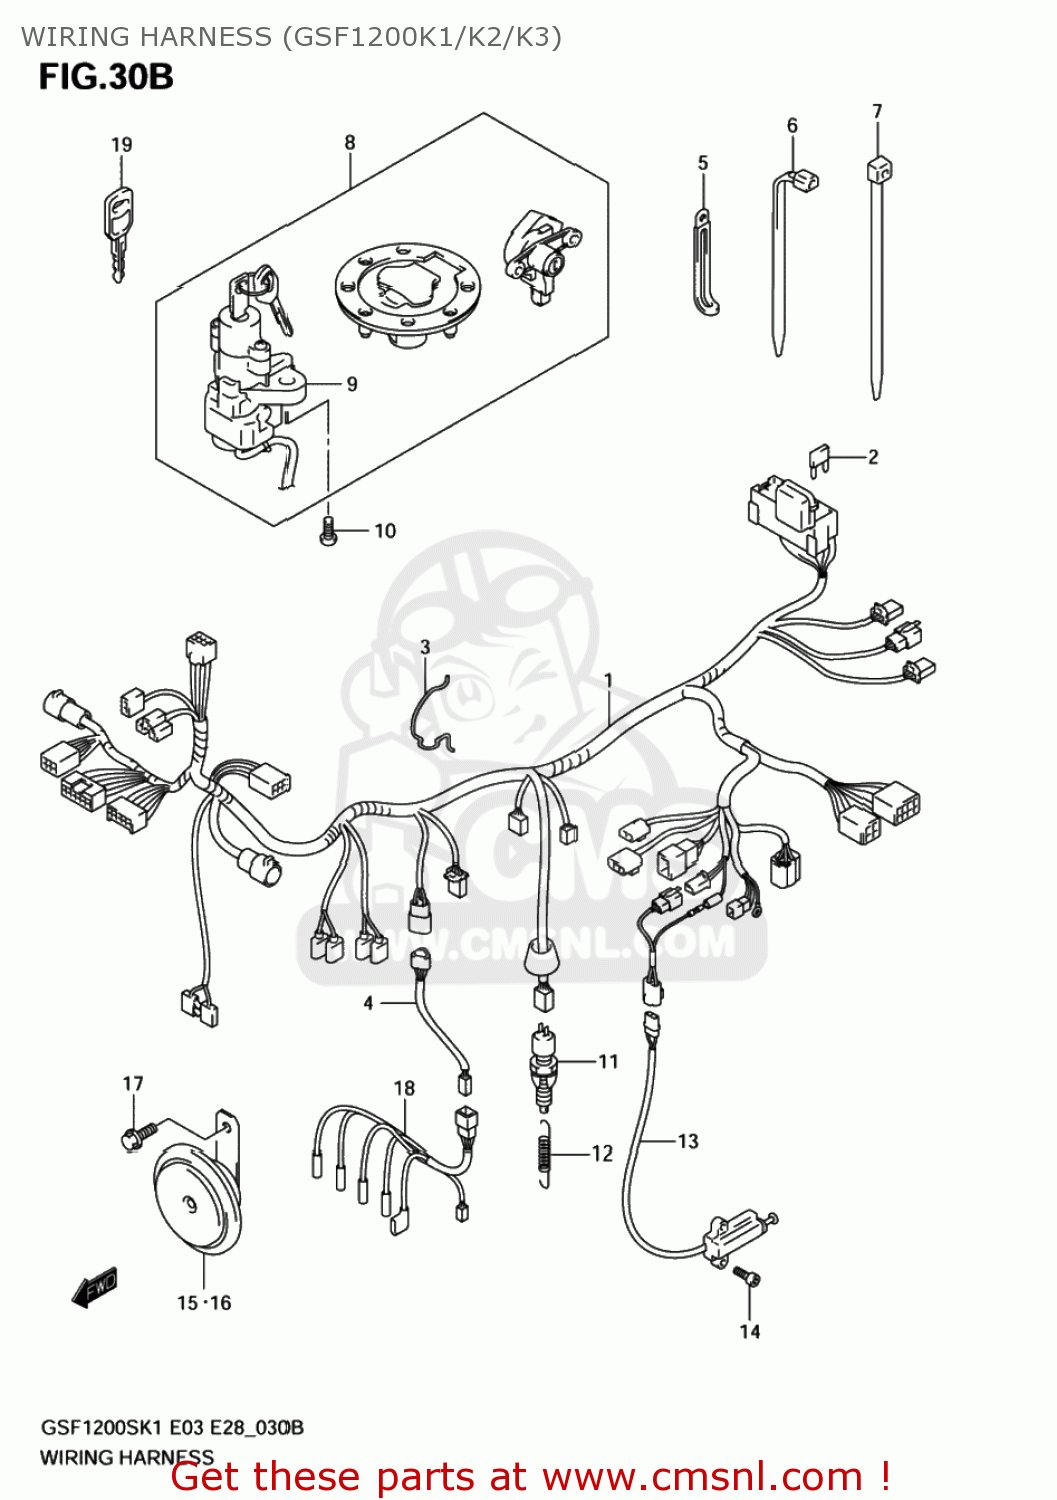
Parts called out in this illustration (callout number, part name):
1	HARNESS,WIRING
2	FUSE(10A)
3	GUIDE,WIRING HARNESS
4	WIRE,TPS LEAD
5	CLAMP(L:80)
6	CLAMP(L:90)
7	CLAMP(L:145)
8	LOCK SET
9	LOCK ASSY,STEE
10	BOLT(8X20)
11	SWITCH ASSY,STOP LAMP
12	SPRING
13	SWITCH ASSY,SIDE STAND
14	BOLT
15	HORN ASSY,LOW PITCHED
16	HORN ASSY,HIGH PITCHED
17	BOLT
18	WIRE,CARB HEATER LEAD
19	KEY,BLANK
